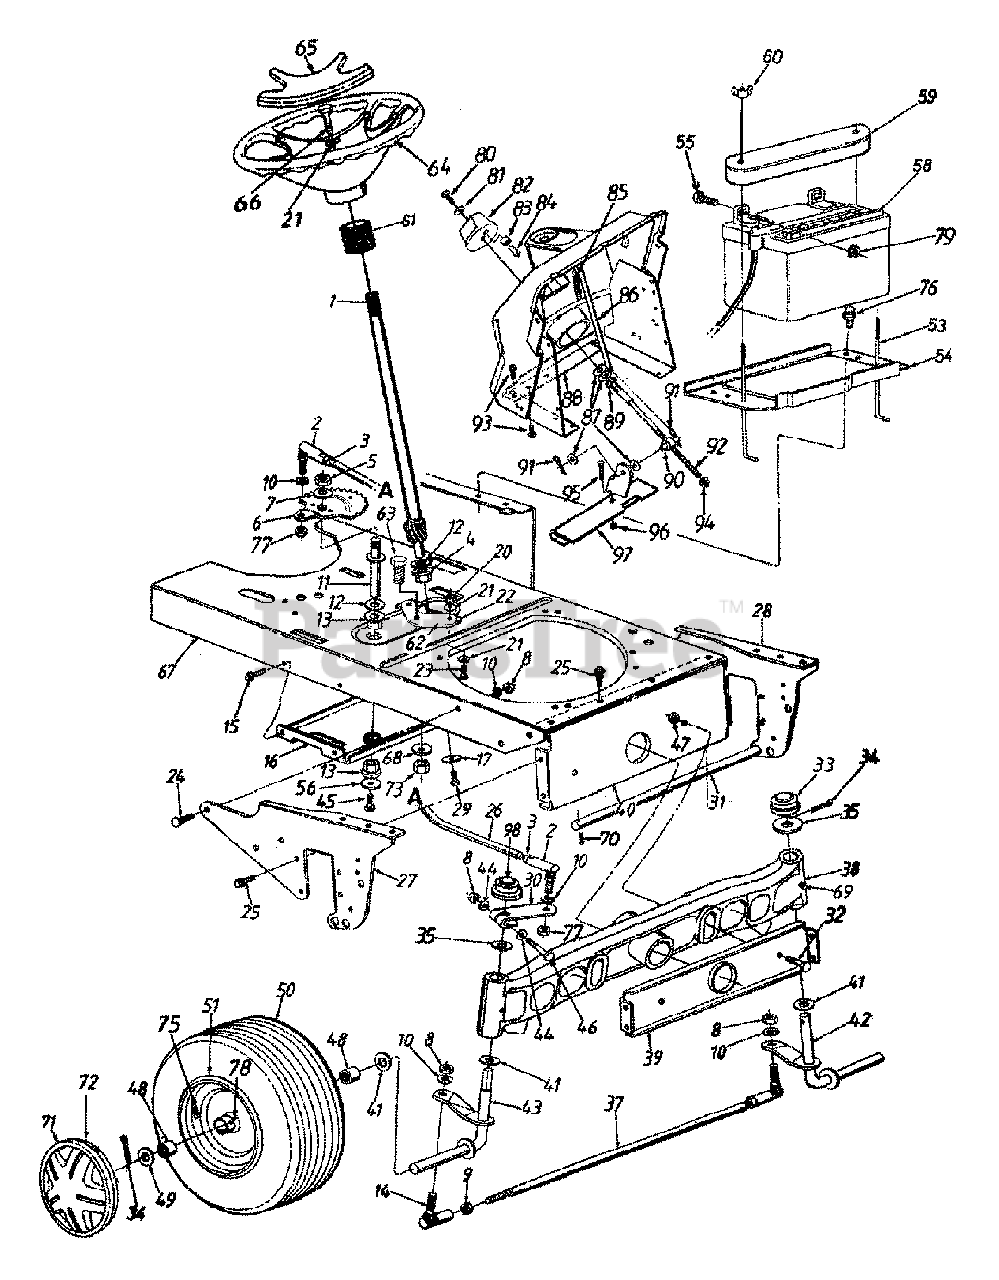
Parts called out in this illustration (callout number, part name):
1	Steering Shaft Ass'y.
2	Ball Joint 7/16-20 Thd.
3	Hex Jam Nut 7/16-20 Thd.
4	Hex Flange Brg.
5	Hex Jam Nut 5/8-18 Thd.
6	Steering Gear Segment
7	Bell-Wash. 5/8" I.D. x 1.25" O.D.
8	Hex Nut 3/8-24 Thd.
9	Hex Jam Nut 3/8-24 Thd.
10	L-Wash. 3/8" I.D.
11	Steering Gear Segment Shaft
12	Fl-Wash. .64" I.D. x 1.24" O.D.
13	Hex Flange Brg. .63" I.D.
14	Ball Joint Ass'y.
15	Hex Wash. Hd. TT-Tap Scr. 1/4-20 x .5" Lg.
17	Cap 1.25" x .16"
20	Hex Nut 5/16-24 Thd.
21	Bell-Wash. .345" I.D. x .88" O.D.
24	Ribbed Neck Bolt 3/8-24 x .8" Lg.
25	Hex Wash. TT-Tap Scr. 5/16-18 x .62" Lg.
26	Steering Drag Link
30	Steering Arm Ass'y.
31	Deck Connecting Rod
32	Shld. Bolt .498" Dia. x 2.45" Lg.
33	Cap
34	Cotter Pin 5/32" Dia.
37	Tie Rod 20.25" Lg.
38	Pivot Bar Ass'y.
41	Fl-Wash. .76" I.D. x 1.49" O.D.
42	Front Axle Ass'y. - L.H.
43	Front Axle Ass'y. - R.H.
44	Bowed Washer
45	Hex L-Scr. 5/16-18 x .62" Lg.
46	Hex Bolt 3/8-24 x 2.25" Lg.
47	Hex L-Nut 3/8-16 Thd.
48	Ball Brg. .75" I.D.
49	Fl-Wash. .71" I.D. x 1.5" O.D.
56	Fl-Wash. .33" I.D. x 1.25" O.D.
58	Battery (275 Cold Crank Amps)
59	Battery Cover
60	Wing Nut Plastic 1/4-20 Thd.
61	Steering Bellow
64	Steering Wheel
65	Steering Wheel Insert
66	Hex L-Bolt 5/16-18 x 1" Lg.
69	Grease Fitting
70	Internal Cotter Pin
71	Hub Cap
72	Spring Clip
73	Hex Nut 3/8-16 Thd.
75	Air Valve
76	Hex Wash. B-Tap Scr. 1/4" x .62" Lg.
77	Hex Jam L-Nut 3/8-24 Thd.
78	Grease Fitting
79	Hex Sems Nut 1/4-20 Thd.
80	Hex Cap Bolt 1/4-20 x .75" Lg.
81	Bell-Wash. .265" I.D. x .75" O.D.
82	Plastic Knob 3" Dia.
83	Spacer .38" I.D. x .5" O.D.
84	Ball Plunger
85	Ext. Spring 4.62" Lg.
86	Indicator Strip Ass'y.
87	Fl-Wash. 3/8" I.D. x .87" O.D.
90	Adjustment Ferrule
91	Hairpin Clip
92	Height Adjustment Rod
93	Hex Wash. TT-Tap Scr. 5/16-18 x .62" Lg.
94	Hex L-Nut 3/8-8 Twin Thd.
95	Hex Bolt 1/4-20 x 1.5" Lg.
96	Hex L-Nut 1/4-20 Thd.
